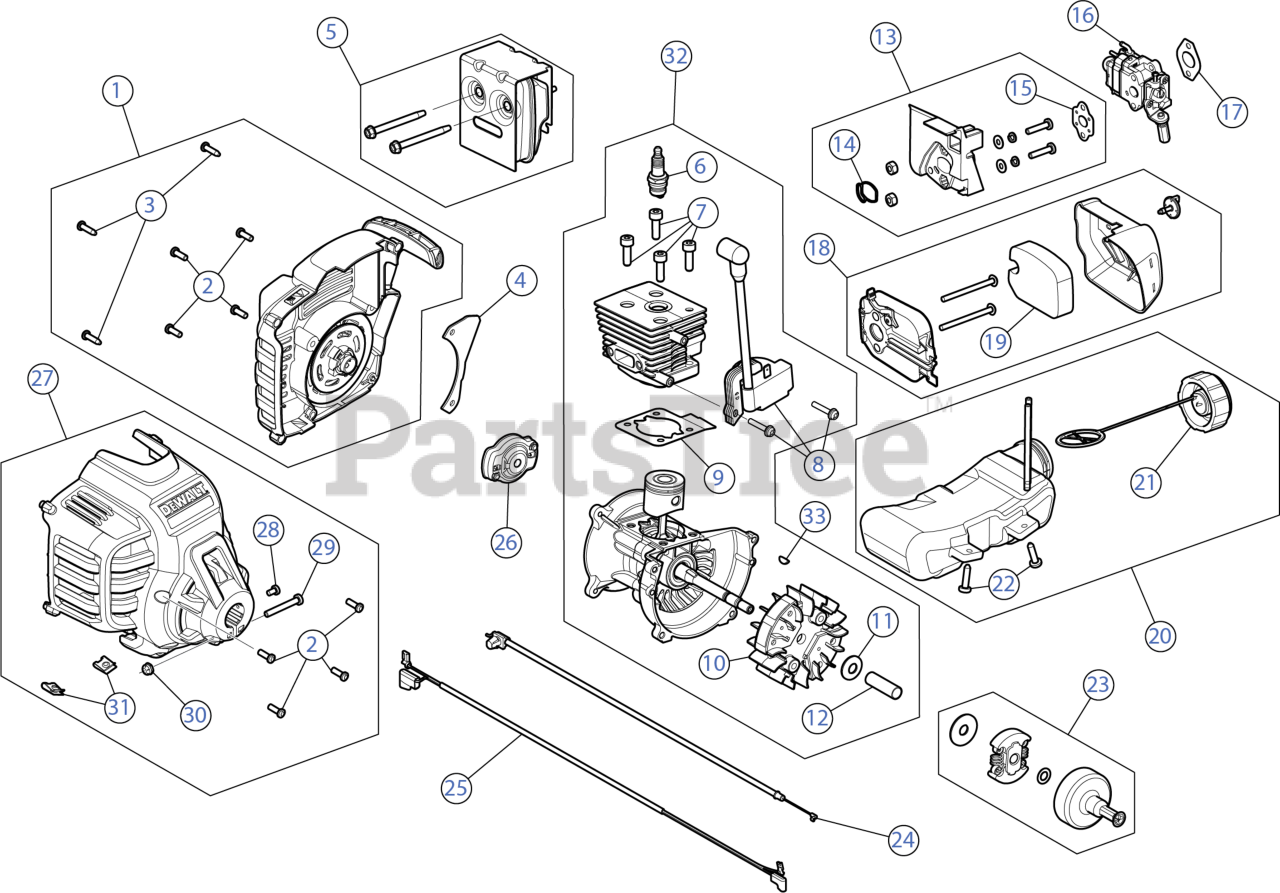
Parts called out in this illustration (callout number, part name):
1	STARTER HOUSING 27CC
2	SCREW #10-24X11/16 T-25
3	SCREW 8-16 x 3/4
4	STARTER GUARD
5	MUFFLER ASSEMBLY
6	SPARK PLUG
7	SCREW 1/4 x 20 x .8125
8	MODULE 27CC
9	GASKET CYL
10	FLYWHEEL ASSEMBLY 27CC
11	BELL WASHER
12	SPACER
13	INTAKE ASSEMBLY
14	O-RING
15	CARBURETOR GASKET
16	CARBURETOR:27CC TRIM ROT
17	GASKET CARB
18	AIR CLEANER
19	AIR FILTER
20	FUEL TANK (W/LINE & CAP)
21	FUEL CAP
22	SCREW:10-6 x .75
23	SMALL CLUTCH ASSEMBLY W/SMALL DRUM
24	THROTTLE CABLE
25	LEAD WIRES
26	PAWL ASSEMBLY AC5
27	CLUTCH COVER
28	SCREW, 8-32 x .312 P
29	SCREW
30	HEX NUT
31	NUT, TINNERMAN U-T
32	SHORTBLOCK
33	WOODRUFF KEY #403-.125 x .375
